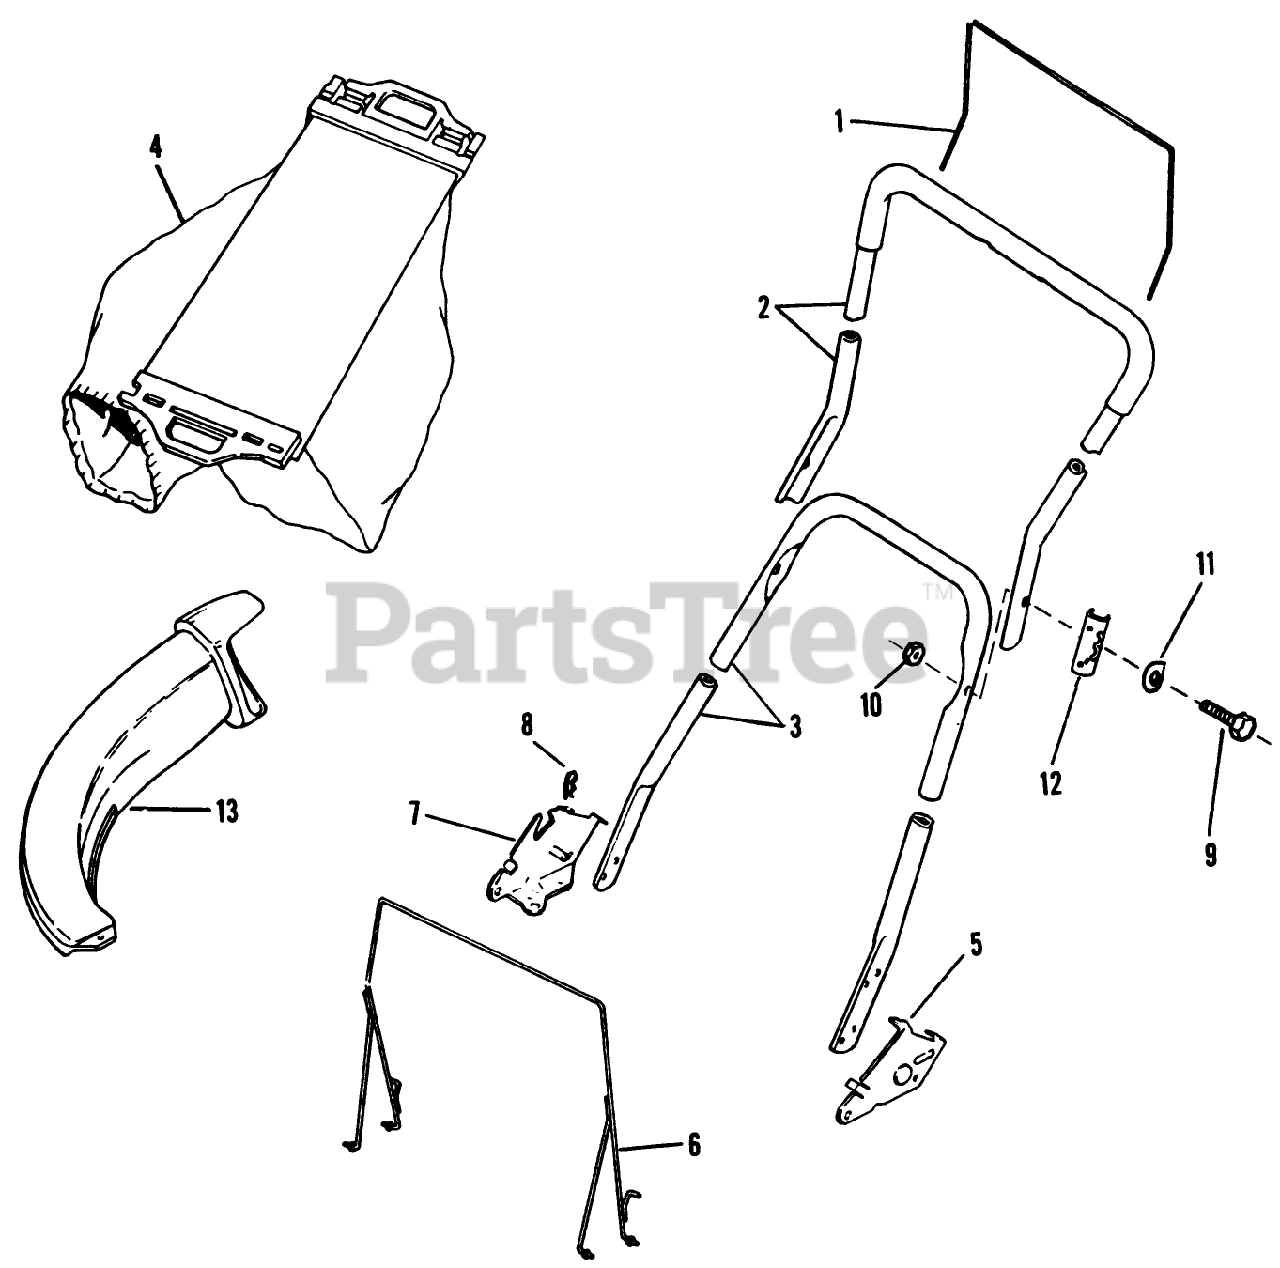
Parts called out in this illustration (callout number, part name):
1	HANGER
3	HANDLE SECTION *B
6	HANGER AY
8	HAIR PIN
10	LOCKNUT E
11	WASHER-CURVED
12	BRACKET R/B 613462
